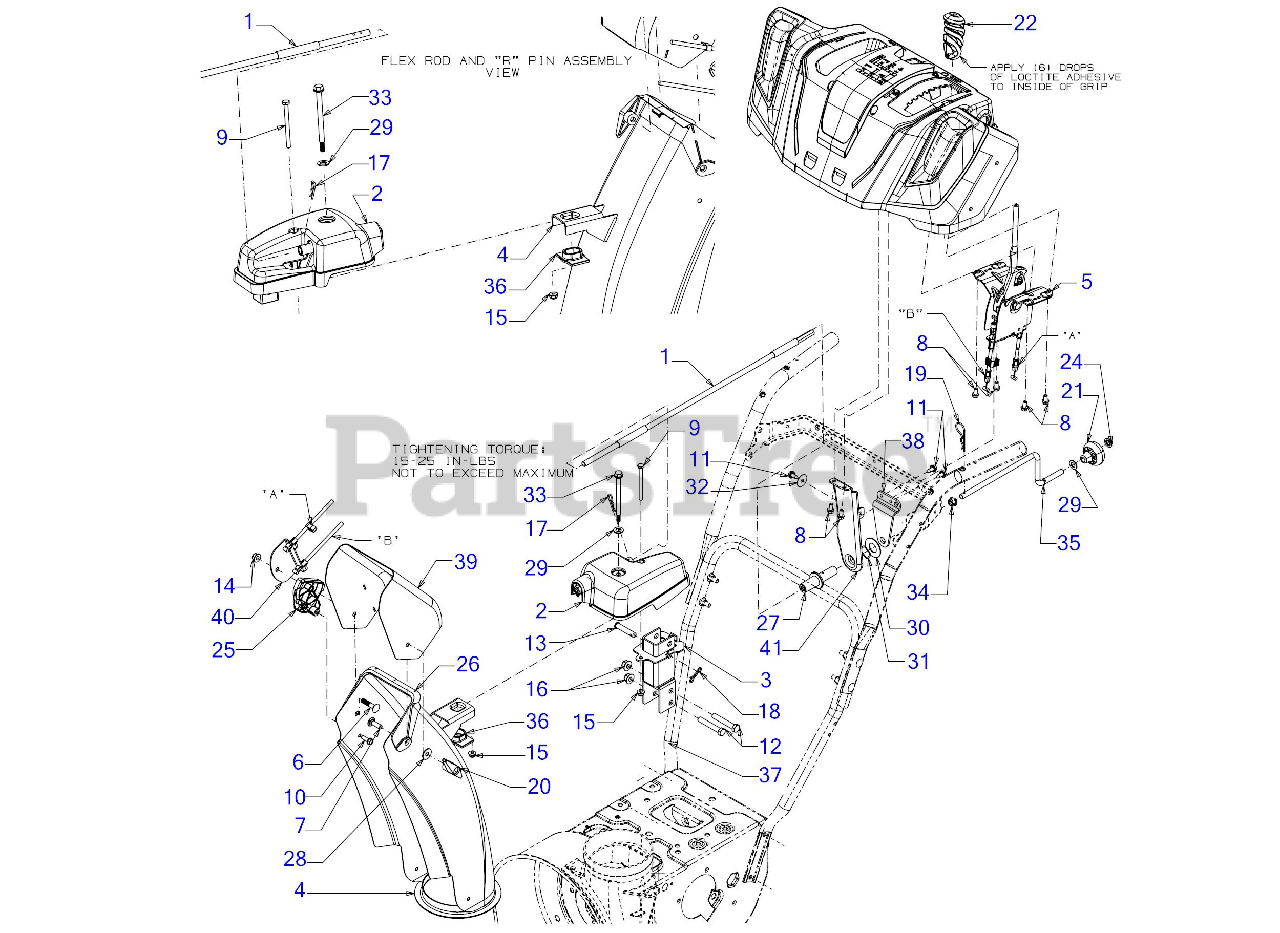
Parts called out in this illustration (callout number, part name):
1	CHUTE CONTROL SHAFT
2	WORM GEARBOX ASSEMBLY
5	2-WAY CHUTE CONTROL ASSEMBLY
6	CARRIAGE BOLT 5/16-18 x 1.50
7	CARRIAGE BOLT 5/16-18 x 1.00
8	HEX SCREW 1/4-15 x .50
9	SCREW 1/4-20 x 3.0 GR5
10	SCREW 1/4-15 x .750
11	SCREW 1/4-20X.625
12	SCREW 3/8-16 x 2.25 GR5
13	CLEVIS PIN 3/8 x 1.87
14	FLANGE LOCK NUT 5/16-18
15	FLANGE LOCK NUT
17	INTERNAL COTTER PIN
18	BOW TIE COTTER PIN 1/4-5/16
19	INTERNAL COTTER PIN
20	WING NUT KNOB
21	SHIFT KNOB
22	PTO HANDLE GRIP .355 ID
24	PUSH NUT
25	CHUTE TILT GUIDE
26	UPPER CHUTE ADAPTER
27	CHUTE ROD COUPLER
28	FLAT WASHER
29	FLAT WASHER
30	FLAT WASHER
31	WAVE WASHER .785X1.00X.012
32	FLAT WASHER
33	SHOULDER SCREW
34	BUSHING .380 ID
36	HELICAL GEAR CHUTE ADAPTER
38	ROD SUPPORT BRACKET
40	CABLE BRACKET GUIDE
41	CHUTE CONTROL BRACKET
